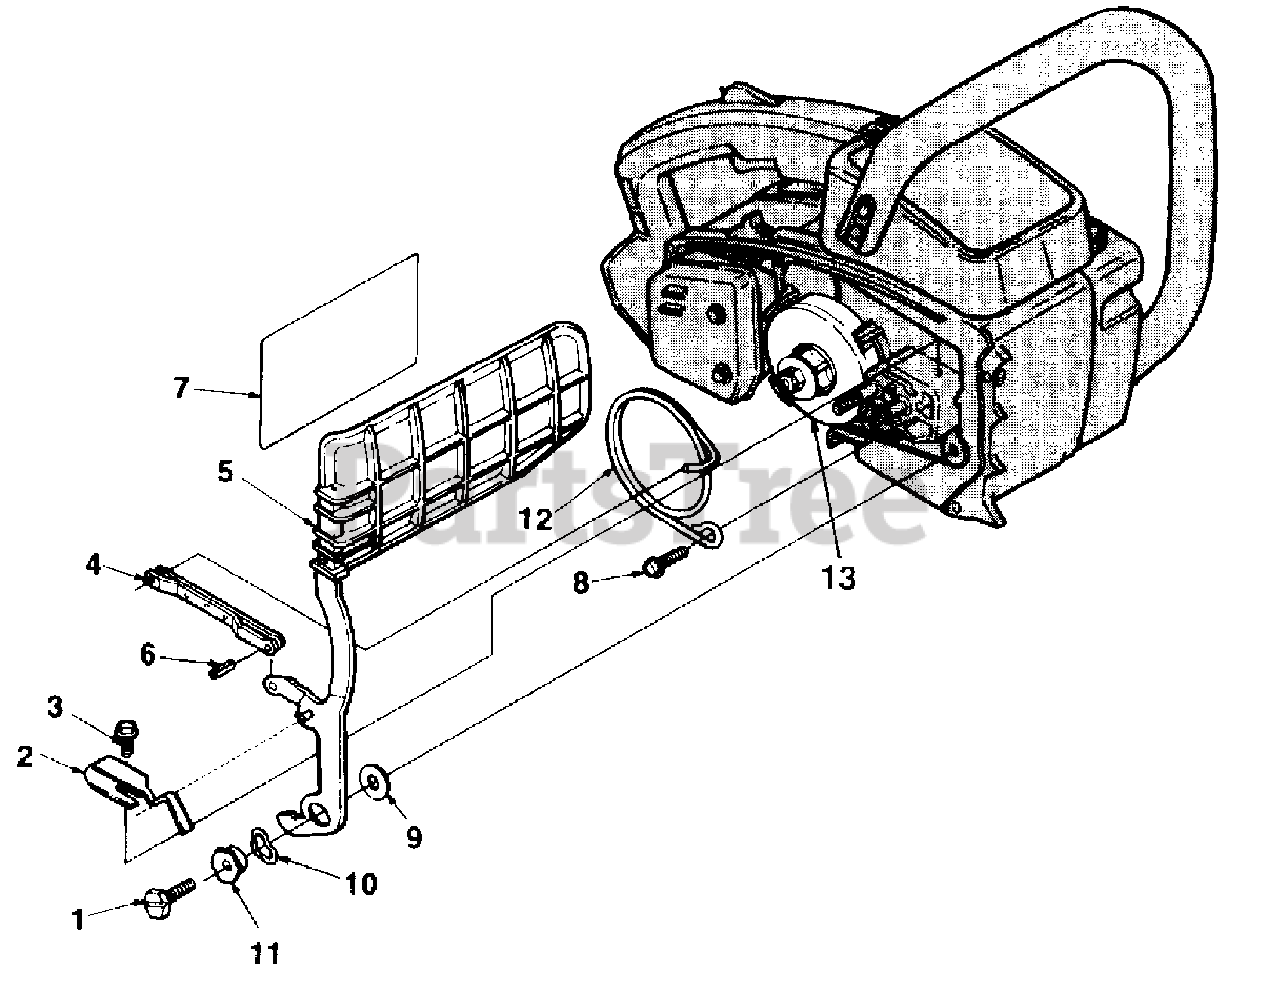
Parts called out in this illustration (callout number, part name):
1	SCREW- Hex cap 1/4-20 x 5/8
2	CLIP- Retaining
3	SCREW- Hex sems 10-24 x 3/8
4	LINK- Pivot
5	HAND GUARD
6	PIN-Roll
7	DECAL
8	SCREW- Hex sems 10-24 x 5/8
9	WASHER- thrust
10	WASHER- Curved
11	CAM- Brake lever
12	BAND- Brake
13	SPROCKET & DRUM (.325P, 8T)
